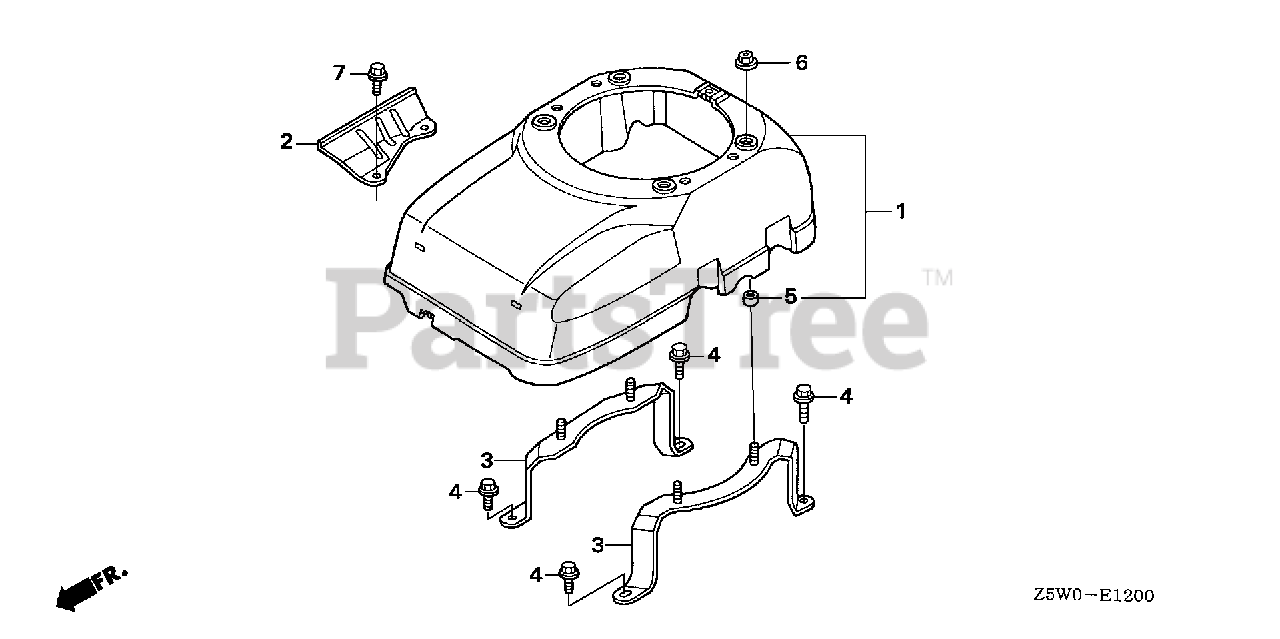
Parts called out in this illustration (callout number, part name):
1	COVER, FAN *NH1* (BLACK)
3	BRACKET, FAN COVER
4	BOLT, FLANGE (6X16) (CT200)
5	COLLAR, FAN COVER
6	NUT, FLANGE (6MM)
